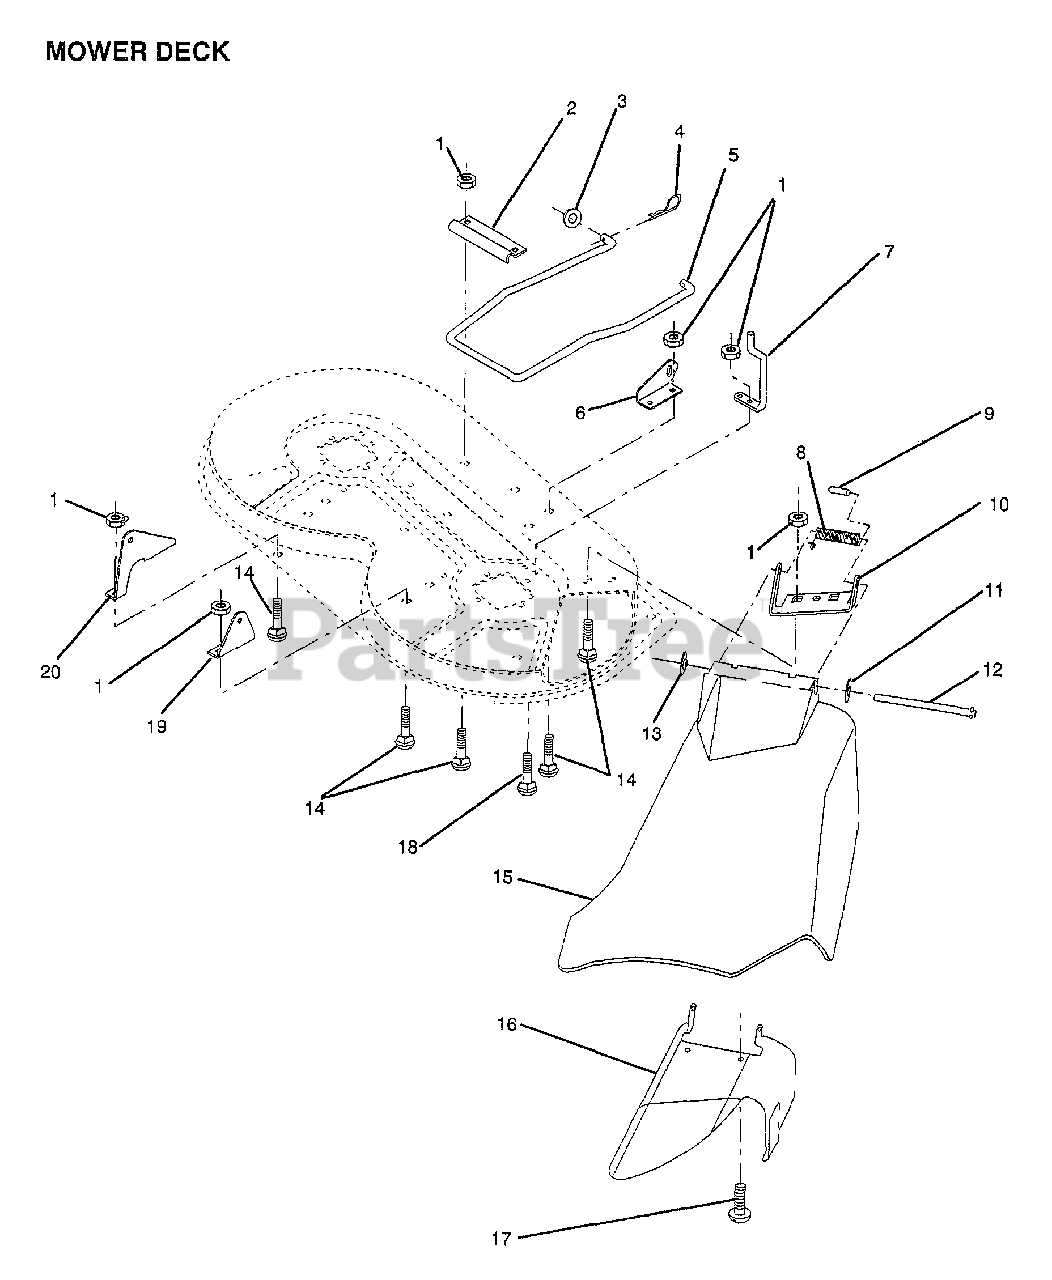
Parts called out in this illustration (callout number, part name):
2	"BRKT,STAB LINK"
4	RETAINER.SPRING
5	STABILIZER MOWER
6	"BRKT,FRT LIFT RH"
7	"GUIDE,FRT MAN RH"
8	SPRING TORSION
9	CAP-SLEEVE LT
11	WASHER
12	HINGE ROD
13	NUT PUSH M
14	BOLT
16	DEFL SUPT ASS'Y
17	SCREW PAN HD
18	BOLT
19	"BRKT,REAR LIFT RH"
20	"BRKT,REAR LIFT LH"
